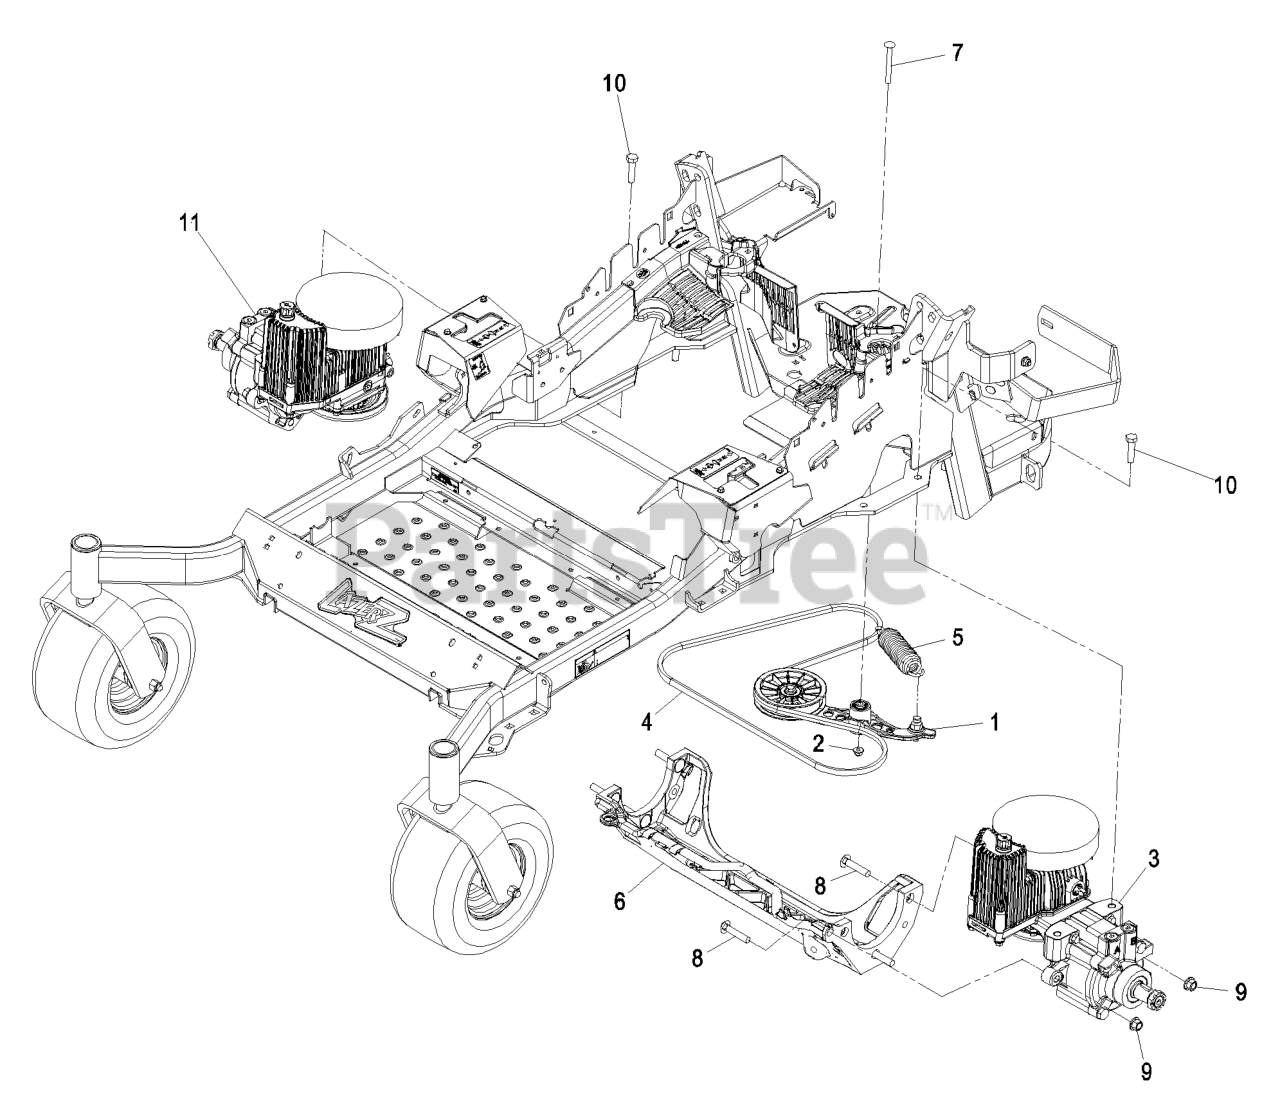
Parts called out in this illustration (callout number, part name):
2	Nut-Nyloc 3/8-16 Flg
4	BELT
7	BOLT-CARRIAGE
8	SCREW-CARR
9	Nut-Lock 1/2-13
10	SCREW-HH
